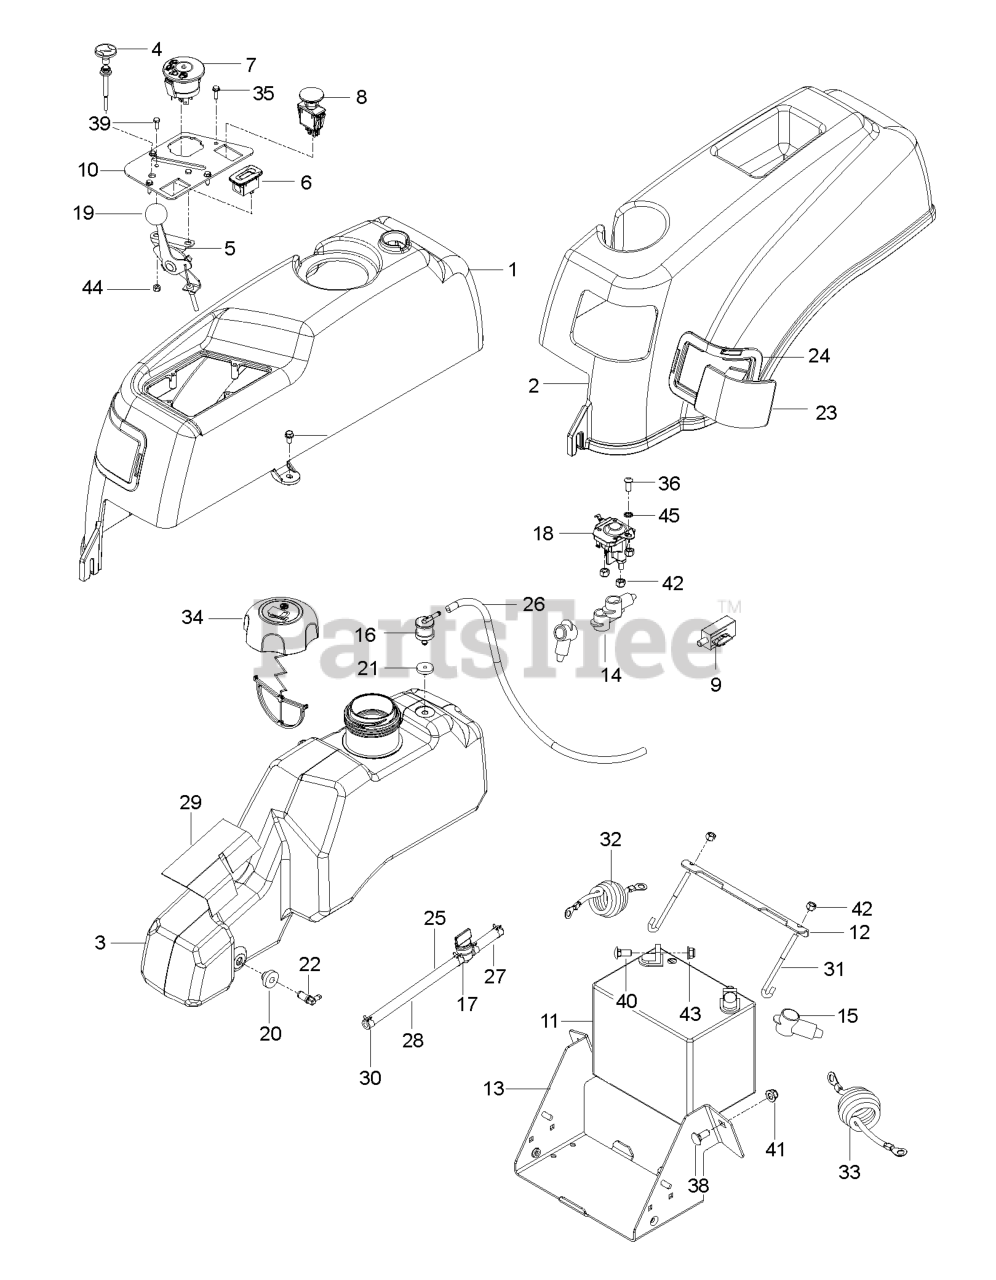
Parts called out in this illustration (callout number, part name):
1	FENDER.RT.BLK.3IN.FUEL.NECK
2	FENDER, LT, BLK
3	FUEL TANK ASSY LARGE 3 NECK TH
4	CHOKE CABLE
5	THROTTLE CABLE
6	GUAGE.SRVCMNDR.HRMTR.
7	IGNITION SWITCH
8	RP SWITCH.PTO.TERMINAL.STD.RED
9	SWITCH.INTRLCK.CLUTCH.
10	CONTROL PLATE RZ STD X431
11	BATTERY, 12 V 330 AMP TBR
12	BRACKET.PNT.MOUNT.BATTERY.EDIP
13	BOX.PNT.BATTERY.RZ.EDIP
14	Terminal Cover (For Solenoid) (AYP part number)
15	INSULATOR
16	VALVE.FUEL.CHECK
17	FUEL VALVE
18	SOLENOID.STARTER.BRASS.PLUNGER
19	KNOB ROUND BALL
20	Bushing (Dana part number) (AYP part number)
21	GROMMET.ROV.SENTEC
22	Stem, Tank Fuel (AYP part number)
23	PANEL, LT
24	RING, LT BLK
25	FUEL.HOSE.SHUT.OFF.ASM.10".3"
26	HOSE.3/16".VAPOR.LINE.20"LGTH
27	HOSE.1/4".LOW.PERM.FUEL.LN.3"
28	HOSE.1/4".LOW.PERM.FUEL.LN.10"
29	SHIELD, HEAT
30	Clamp Hose Black (AYP part number)
31	HOOK.J.BATTERY
32	CABLE BATTERY GROUND RZ
33	CABLE BATTERY POS RZ
34	CAP ASSY FUEL 3" BLACK
35	SCR #10-12X3/4 HEX WAS HD ZD
36	SCR 1/4-20 X 5/8 BTN SKT HD ZD
37	SCREW
38	RHSNB 3/8C X 1
39	HCS #10-24 X 1/2
40	BOLT 5/16C X 3/4" CARRIAGE
41	NUT 10-24 NYLOC
42	NUT 1/4-20 NYLOC
43	5/16-18 NYLOC FLANGE NUT
44	NUT 3/8-16 HEX FLG NYLOC ZD
45	WASHER 1/4 INT TOOTH
